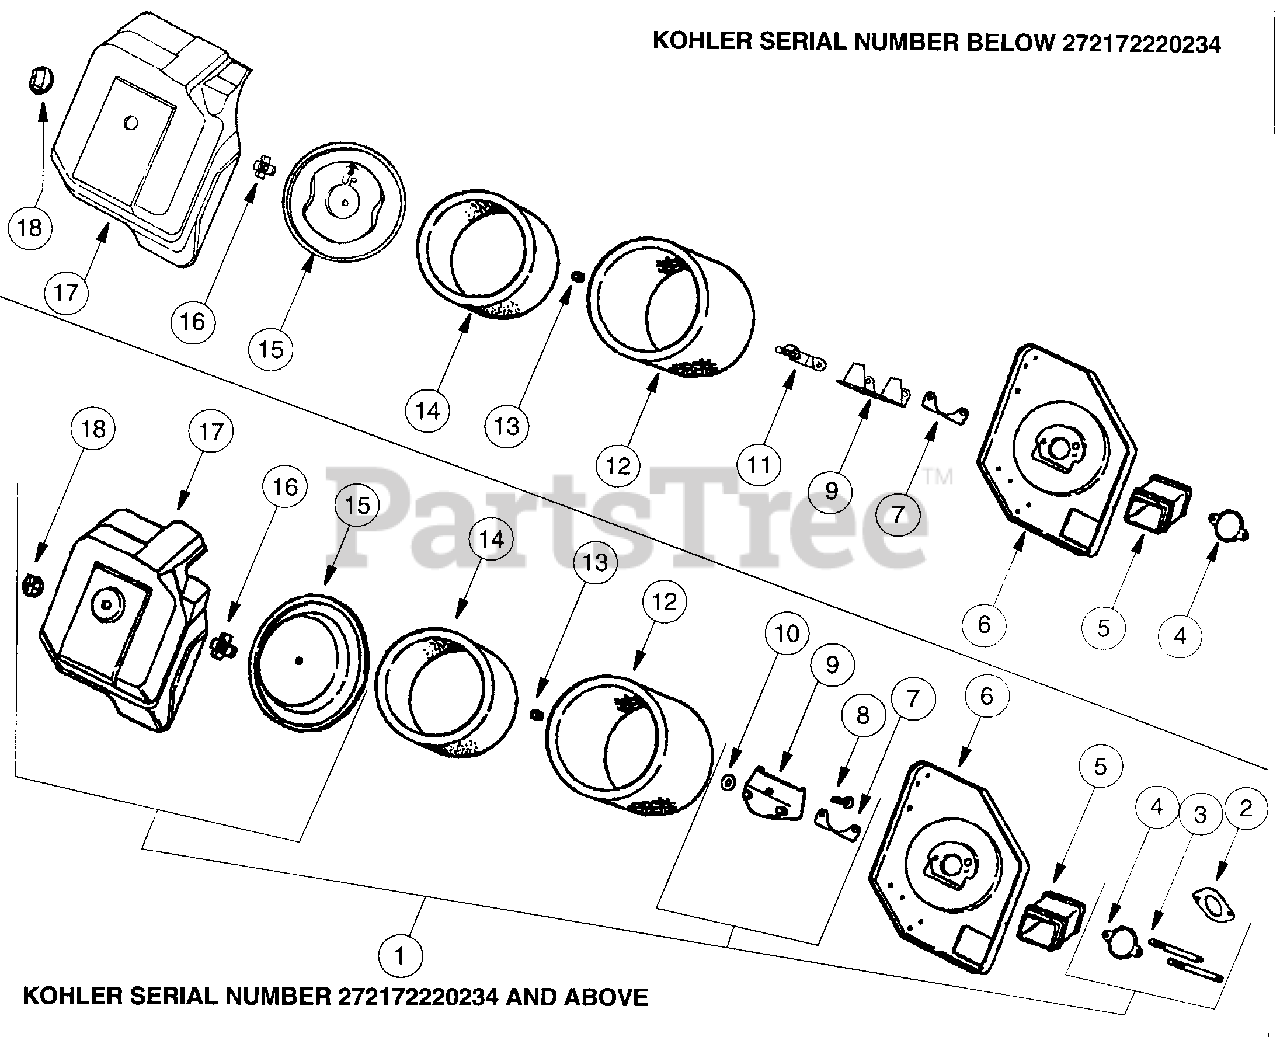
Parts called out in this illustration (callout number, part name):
1	Kit, Fuel Recovery
2	Gasket, Carburetor
3	Stud, M6 x 1.0 x 116
4	Gasket, Air Cleaner
5	Tube, Air Cleaner
6	Base, Air Cleaner
7	Gasket, Collector Plate
8	Bolt, Carriage, M6 x 1.0 x 22
9	Plate, Air Cleaner
10	Retainer, Ring
11	Bracket, Air Cleaner
12	Element, Air Cleaner
13	Seal, Inner Air Cleaner
14	Pre-Cleaner, Element
15	Cover, Air Cleaner Element
16	Wingnut, Element Cover
17	Cover, Air Cleaner Base
18	Knob, Air Cleaner Cover
